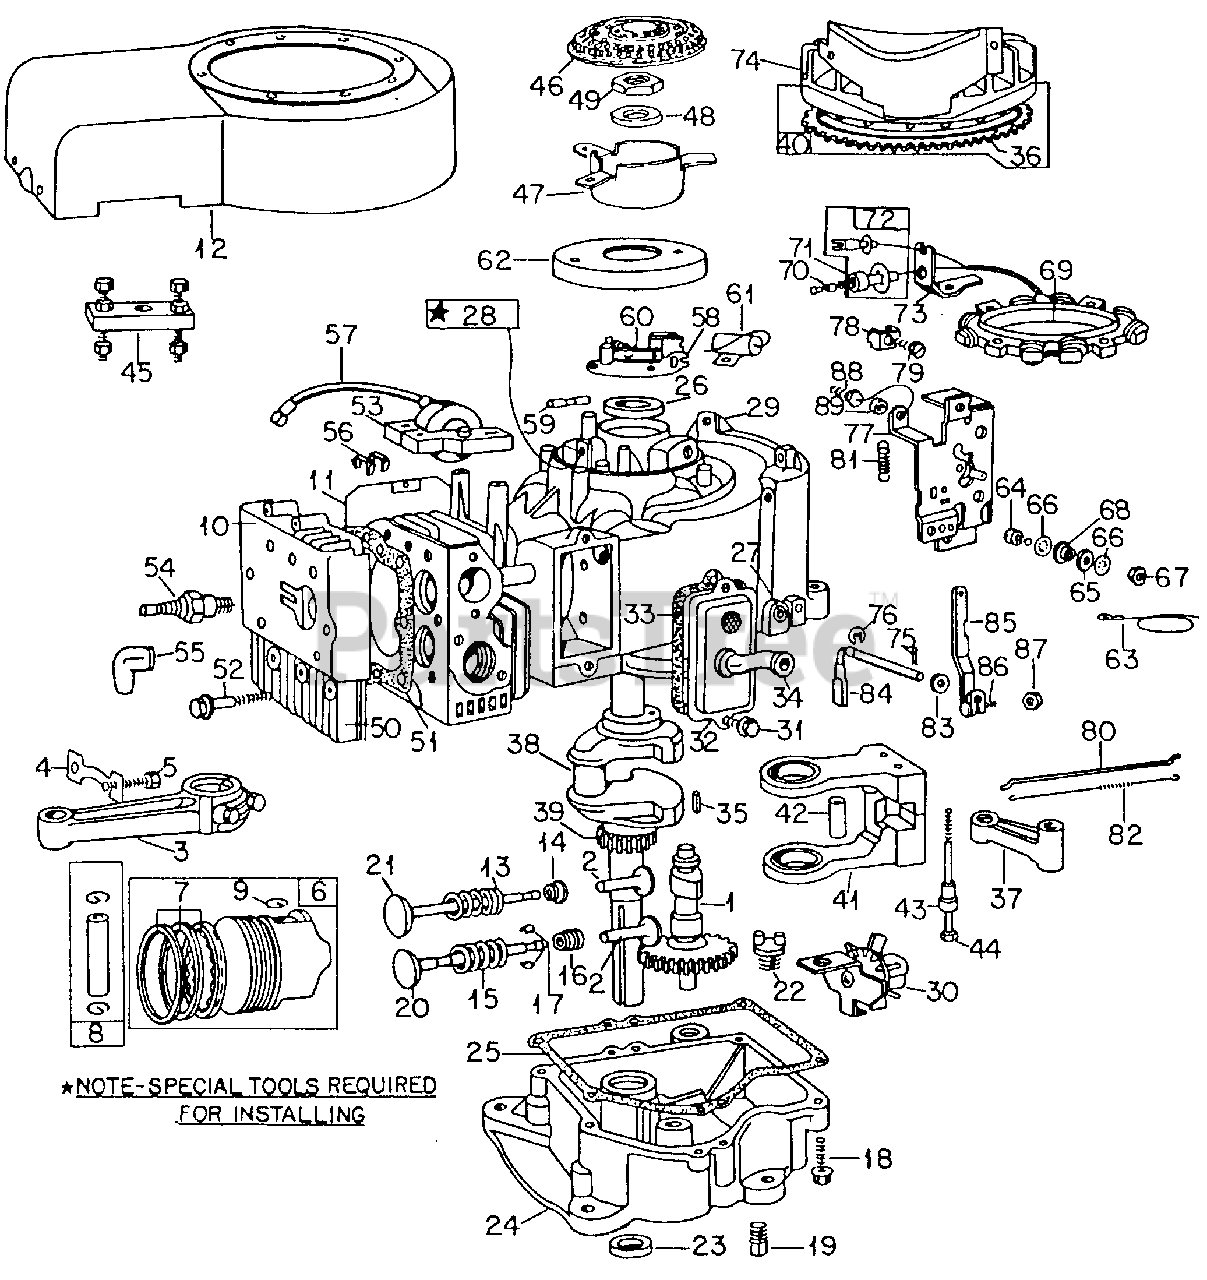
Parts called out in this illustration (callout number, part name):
1	Camshaft w/Gear
2	Tappet, Valve
3	Rod Assy, Connecting
4	Lock, Screw Head
5	Screw, Connecting Rod
6	Piston Assy, Std
7	Set, Piston Ring, Std
8	Pin Assy, Piston
9	Ring, Piston Pin Lock
10	Cover, Cylinder Head
11	Shield, Cylinder
12	Housing, Blower
13	Spring, Intake Valve
14	Retainer, Intake Valve
15	Spring, Exhaust Valve
16	Retainer, Roto-Coil
17	Roto-Coil, Exhaust Valve
18	Screw, Sump Mounting
19	Plug, 3/8-18 Automotive Sq Hd Oil Drain
20	Valve, Exhaust
21	Valve, Intake
22	Plug, Oil Filler
23	Seal, Oil
24	Cover, Crankcase Oil Sump
25	Gasket, Crankcase
26	Seal, Oil
27	Bushing, Governor
28	Bushing, Plunger
29	Cylinder Assy
30	Oil Slinger, Governor Gear
31	Screw, Breather Mounting
32	Breather, Valve Chamber
33	Gasket, Breather & Valve Chamber
34	Tube, Breather
35	Key, Flywheel
36	Gear, Ring
37	Link, Counterweight
38	Crankshaft
39	Gear, Timing
40	Flywheel w/Ring Gear Assy
41	Counterweight Assy
42	Pin, Counterweight
43	Spacer, Counterweight
44	Screw, Counterweight
45	Puller, Flywheel
46	Screen, Flywheel
47	Cup, Screen Mounting
48	Washer, Spring
49	Nut, 5/8-NF
50	Head, Cylinder
51	Gasket, Cylinder Head
52	Screw, Cylinder Head
53	Armature Assy, Magneto
54	Plug, Spark (Champion)
55	Elbow, Spark Plug Insulator
57	Terminal, Magneto Cable
58	Breaker Assy, Ignition
59	Plunger, Breaker Points
60	Spring, Breaker Arm
61	Condenser
62	Cover, Points & Condenser
63	Wire, Ground
64	Screw, No. 8 X 5/8 Mach Ground
65	Washer, Insulating
66	Washer, Internal Tooth Lock
67	Nut, No. 8 Mach
68	Collar, Insulating
69	Stator, Alternator
71	Spring, Diode
72	Holder, Fuse
73	Bracket, Fuse
74	Cover, Starter Shield
75	Cotter, Governor Crank
76	Retainer, Governor Crank
77	Plate, Governor
78	Clamp, Casting
79	Screw w/Lock Washer
80	Link, Governor
81	Spring, Governor
82	Spring, Governor Link
83	Washer, Governor Crank
84	Crank, Governor
85	Lever Assy, Governor
86	Bolt, Governor Lever
87	Nut, No. 10 Mach
88	Screw, Governor Control Plate Mounting
